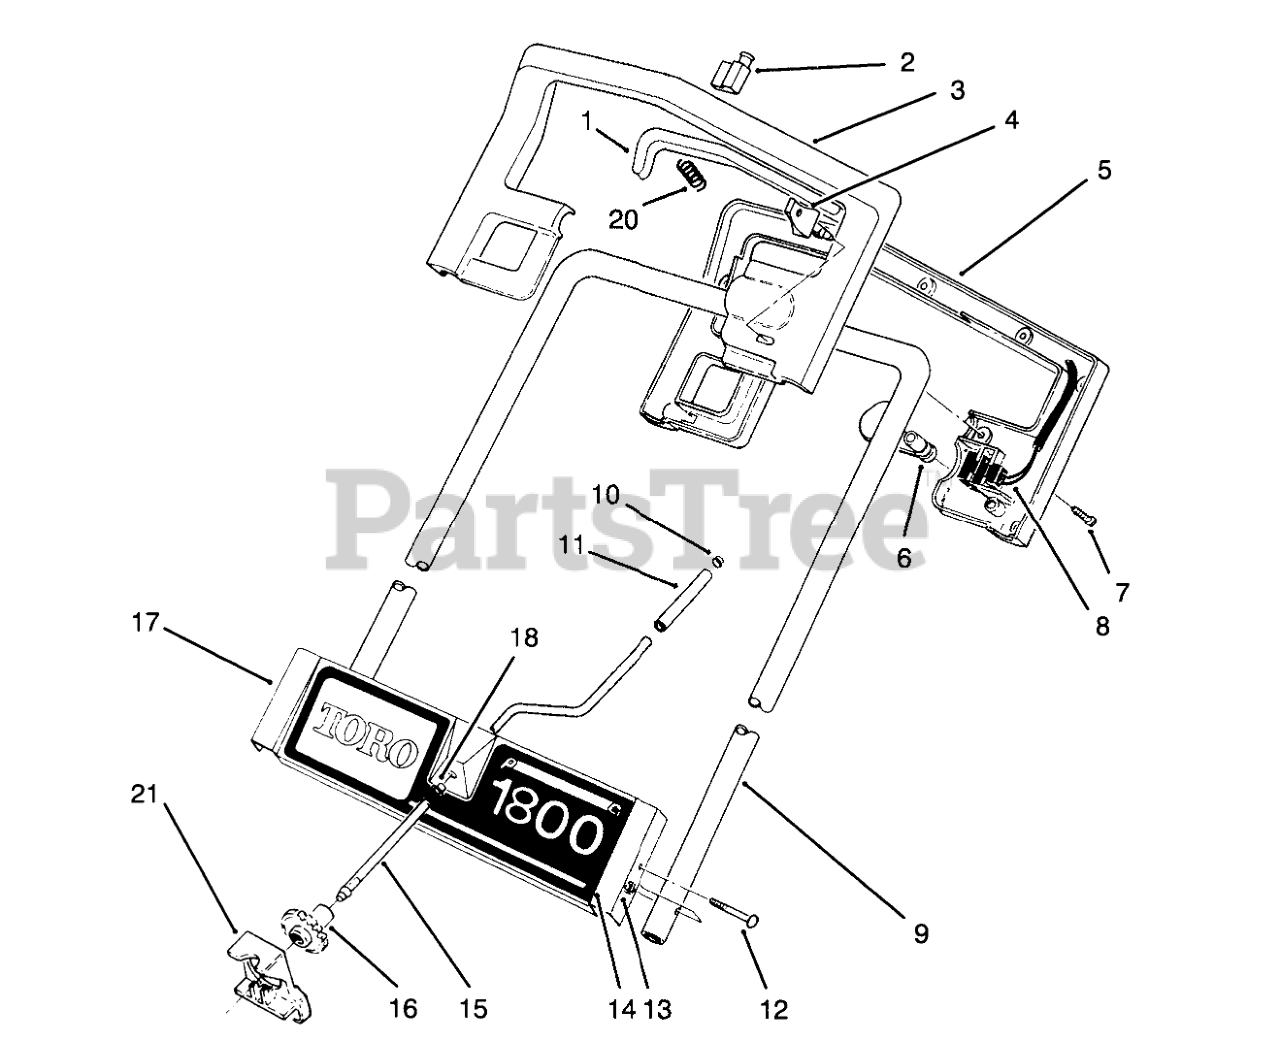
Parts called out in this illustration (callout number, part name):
1	Bar-Switch
2	SWITCH
3	Handle-Control, Upper
5	Handle-Control, Lower
6	Tab-Lock
7	Screw
8	Cord-Supply
9	Tube-Handle, Upper
10	PUSHNUT-CAP, WASHER
11	Sleeve-Crank, Chute
12	Screw-HH
13	NUT-LOCK, NI
14	DECAL - ESCUTCHEON
15	Rod-Crank, Chute
16	Gear-Crank, Chute
17	Plate-Escutcheon
18	Bushing-Nyliner
20	Spring
21	Brake-Gear
